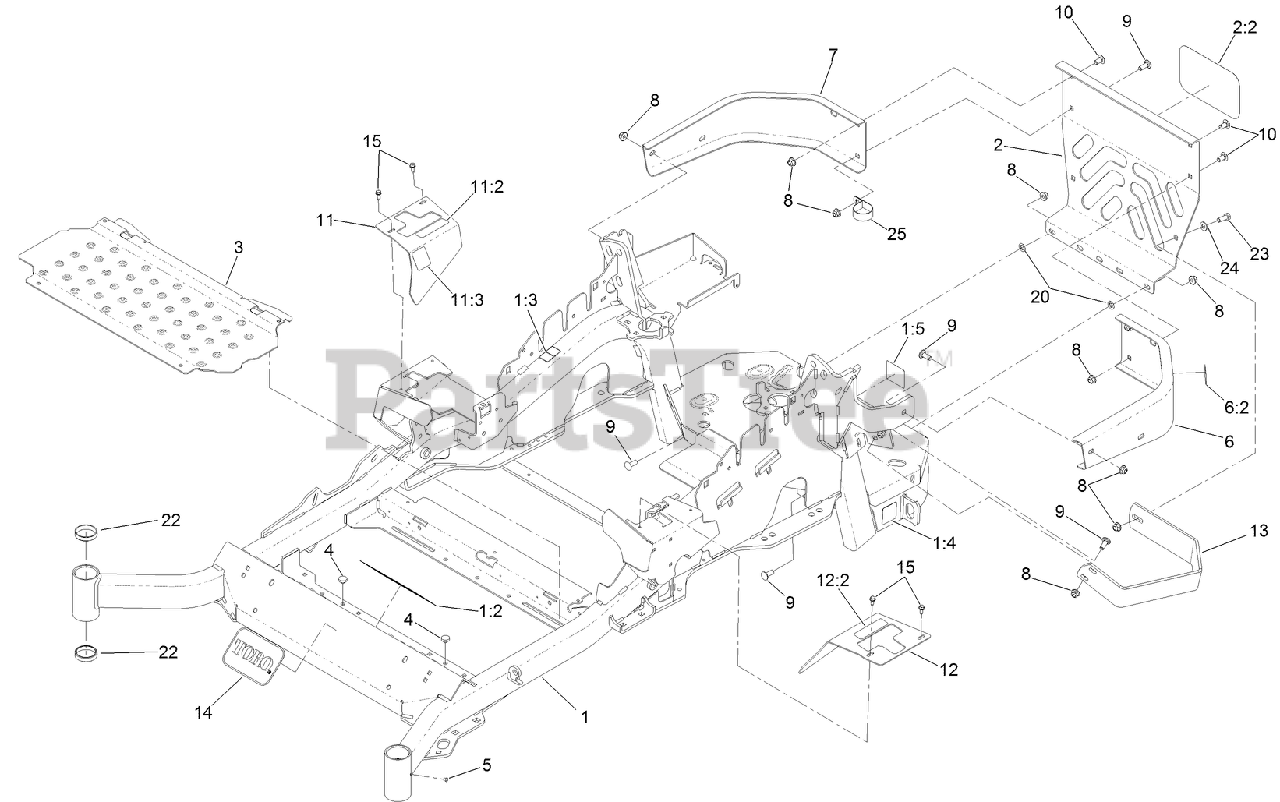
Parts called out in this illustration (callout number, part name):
1	MAINFRAME ASM
1:2	DECAL-DANGER
1:3	DECAL-WARNING
1:4	DECAL-HAZARD, PINCHED FINGER
1:5	DECAL-ARRESTOR, SPARK
2	REAR GUARD ASM
2:2	DECAL
3	FLOORPAN
4	BUMPER
6	LH BUMPER ASM
6:2	DECAL-WARNING
7	BUMPER-RH
8	NUT-HF, NI
9	SCREW-CARR
10	SCREW-CARR
11	RH MOTION CONTROL COVER ASM
11:2	DECAL-CONTROL, MOTION
11:3	DECAL-PARK BRAKE, CE
12	LH MOTION CONTROL COVER ASM
12:2	DECAL-CONTROL, MOTION
13	GUARD-MUFFLER
14	DECAL
15	SCREW-HWH
20	NUT-PUSH
22	CUP-BEARING
23	SCREW-HH
24	WASHER-FLAT
25	CLAMP-R
